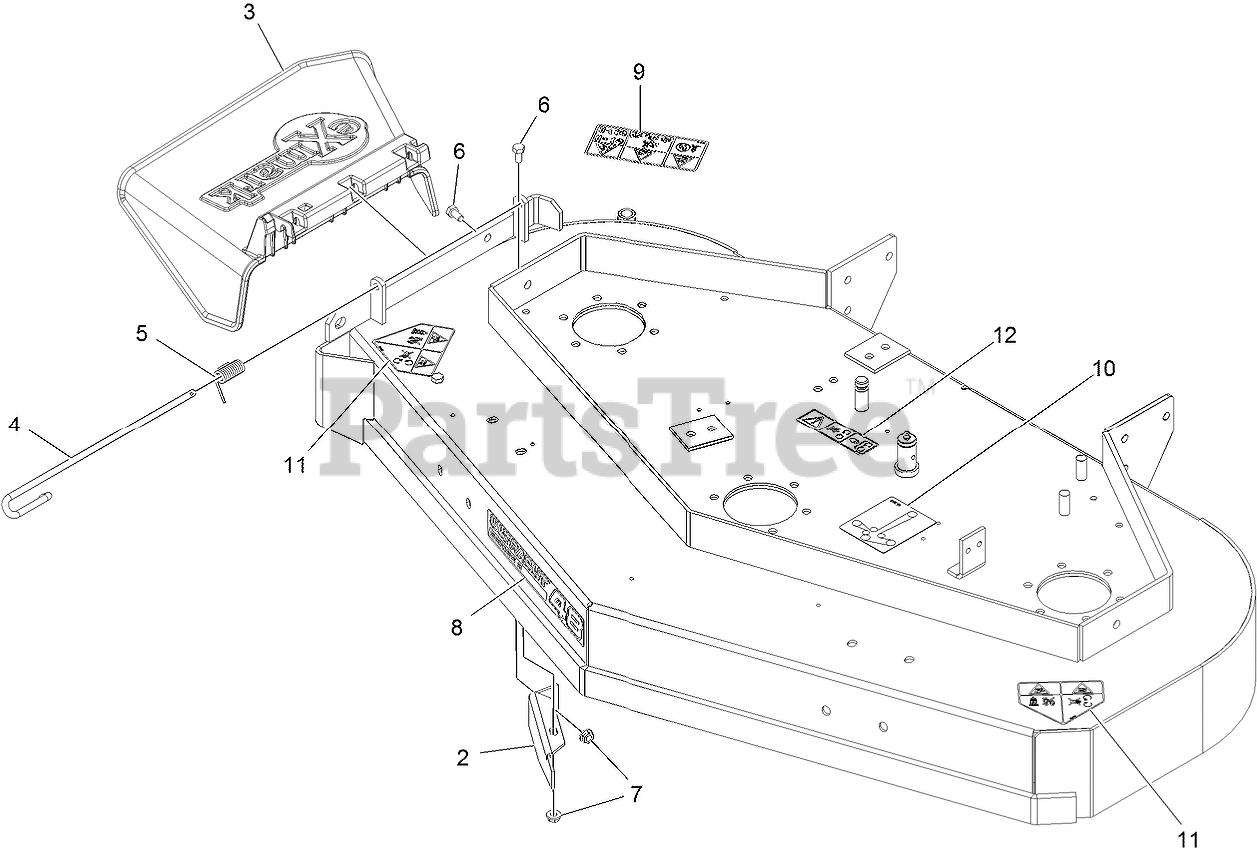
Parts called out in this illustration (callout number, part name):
2	BAFFLE-DOGLEG
3	CHUTE DEFLECTOR XRK M056
4	PIN-CHUTE
5	SPRING, TORSION
6	SCREW-HH
8	DECAL-ULTRACUT 48 SERIES
9	DECAL-WARNING THROWN OBJ
10	DECAL-ROUTING, BELT
11	DECAL-DANGER
12	DECAL-COVER, MISSING
